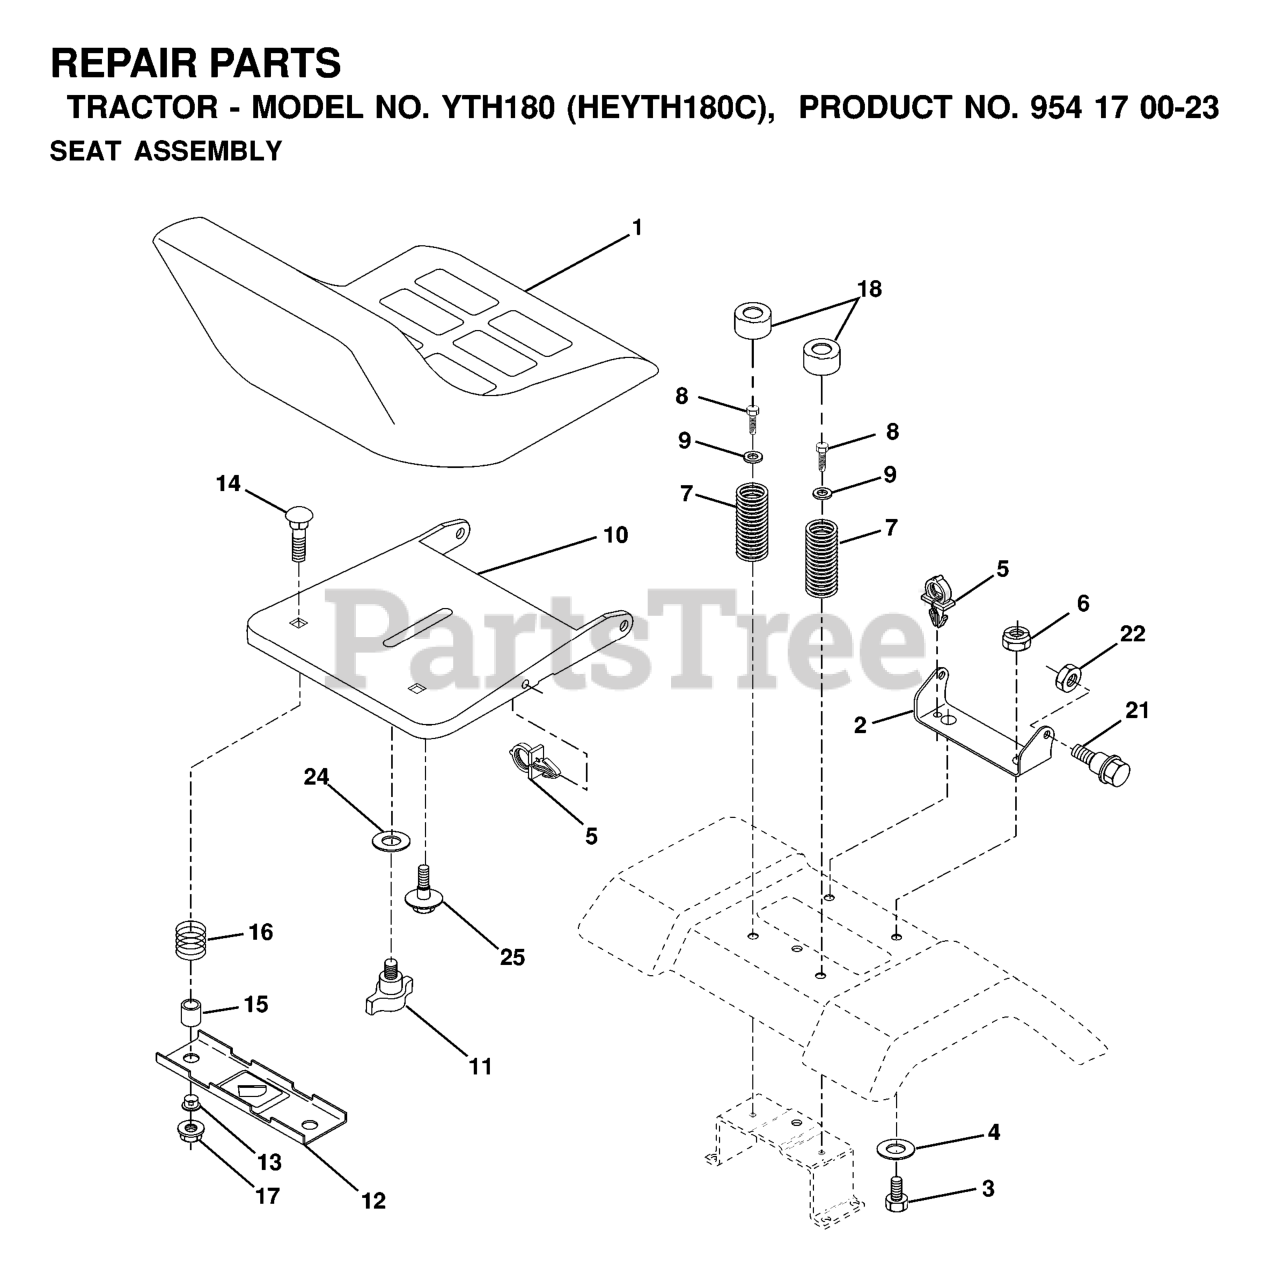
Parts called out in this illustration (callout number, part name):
1	SEAT, GRAY
2	SEAT PIVOT BRKT
3	BOLT, HEX 3/8-16X1
6	NUT
7	SPRING COMPRESSION
8	SCREW 3/8-16X1
9	WASHER
10	PAN, SEAT
11	KNOB.SEAT.ADJ.WINGNUT
12	BRKT SWITCH
14	BOLT.ROUND.HEAD.SQUARE.NECK
15	SPACER SPLIT
16	SPRING COMPRESSED
17	NUT T
18	CAP SPRING
21	BOLT SHOULDER 5/16-18
22	NUT.71038.31-18.HEX.NYLOCK
25	BOLT,SHOULD
